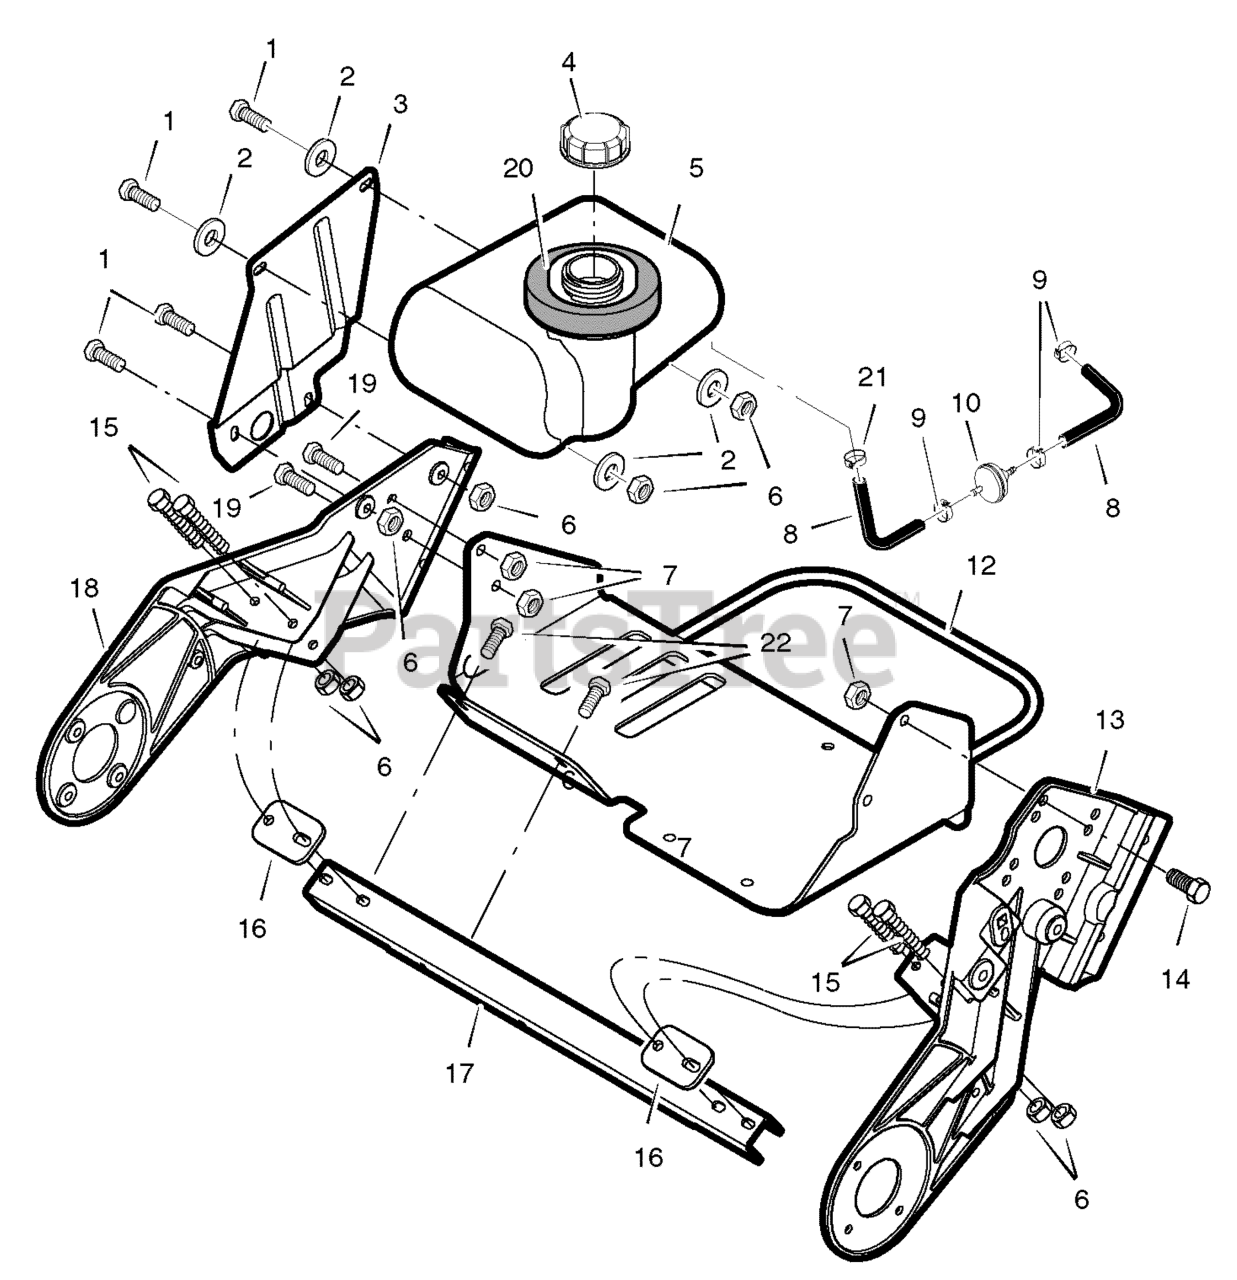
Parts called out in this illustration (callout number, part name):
1	Screw, 1/4-20 x .75
2	Washer, Flat .286x.63x.065
3	Bracket, Fuel Tank
4	Cap, Fuel Tank
5	Tank, Fuel
6	NUT, 1/4-20 REGHEXCTRLK YZ
7	Locknut, Hex Center 5/16-18
8	TUBING, Fuel Line
9	CLAMP, FUEL LINE
10	Filter, Fuel Line
11	Tubing, Fuel LIne
12	Cradle Assembly, Engine
13	Frame, LH
14	Screw, 5/16-18 x 0.63
15	SCREW, 1/4-20 x 2.00
16	Plate, Mounting Support
17	Support, Frame
18	Frame, RH
19	Screw, 5/16-18 x 0.75
20	Ring, Foam
21	Clamp, Fuel Line -Screw Type
22	SCREW, TAP 1/4-20 X .63
